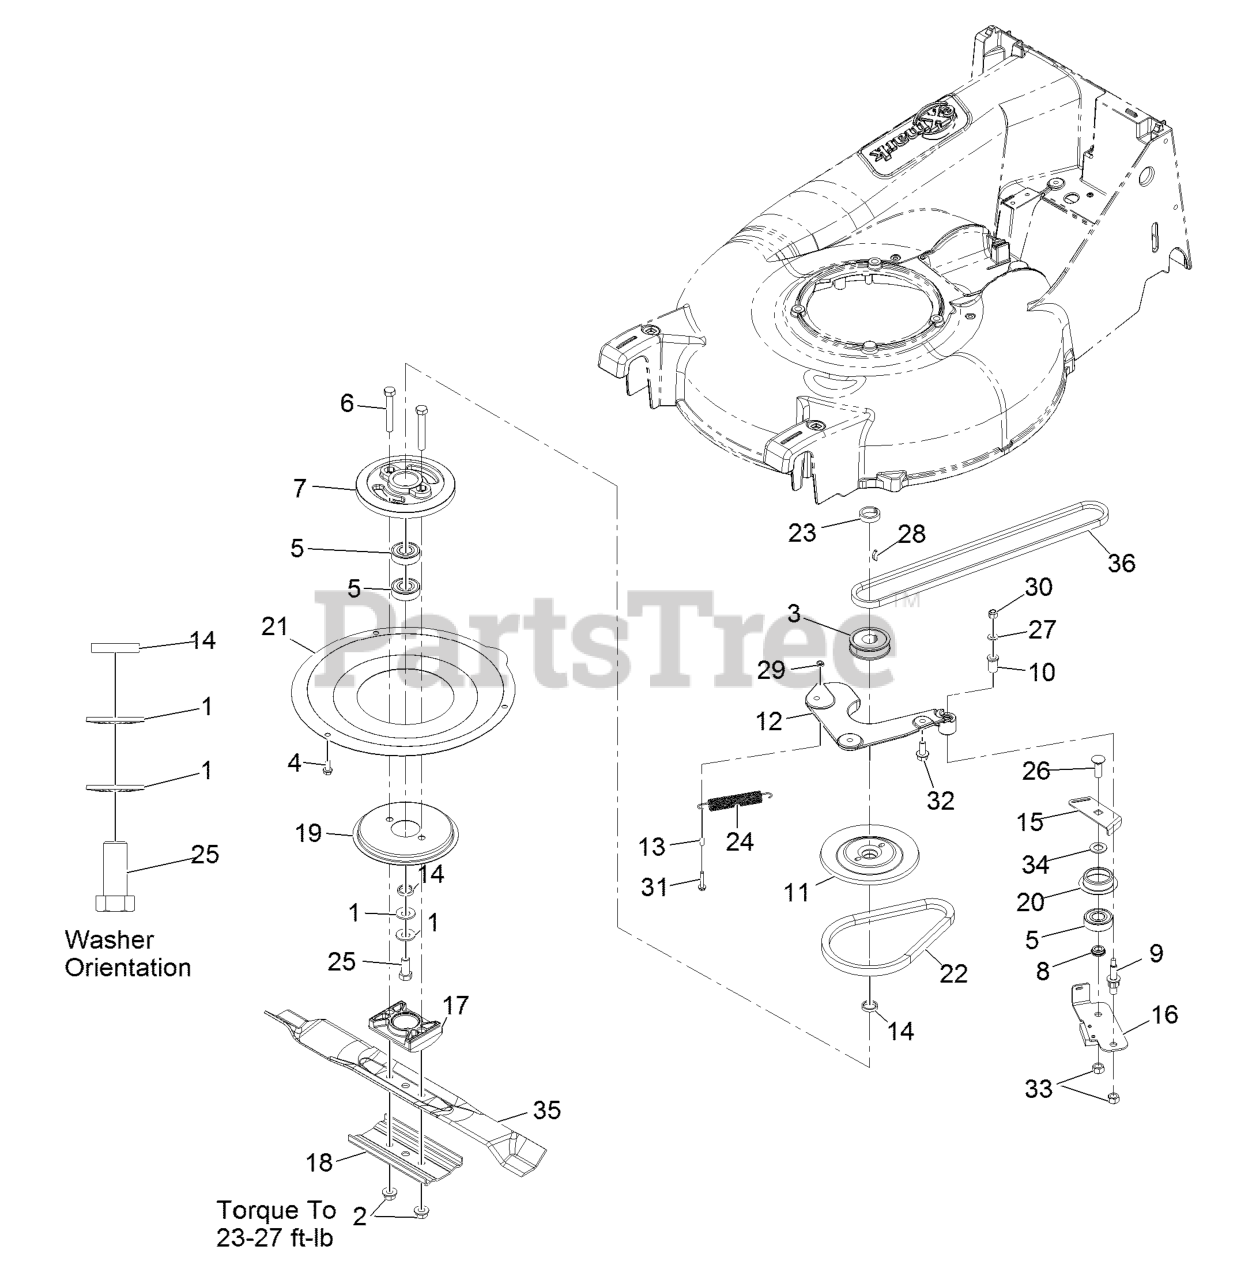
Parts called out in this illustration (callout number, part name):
1	WASHER-SPRING
2	Nut-Hex 3/8-24 Lock
3	PULLEY-DRIVER
4	SCREW-HWH
6	SCREW-HH
8	SPACER-BEARING
9	BOLT-SHOULDER
10	BUSHING
11	PULLEY-DRIVER, UPPER
12	PLATE-MOUNTING, BBC
13	SPACER-BBC
14	SPACER-PLATE, BBC
15	PLATE-GUIDE
17	SUPPORT-BLADE
18	SUPPORT-BLADE
19	DISC
20	RETAINER-BELT
21	COVER-BBC
22	BELT
23	SPACER-PULLEY
24	SPRING-EXTENSION
25	SCREW-HH
26	SCREW-CARR
27	WASHER-FLAT
28	KEY-WOODRUFF
29	NUT-LOCK, NI
30	NUT-LOCK, NI
31	SCREW-TAP
32	SCREW-HHF
33	LOCKNUT
34	SPACER
36	BELT,3L P21 DRIVE
